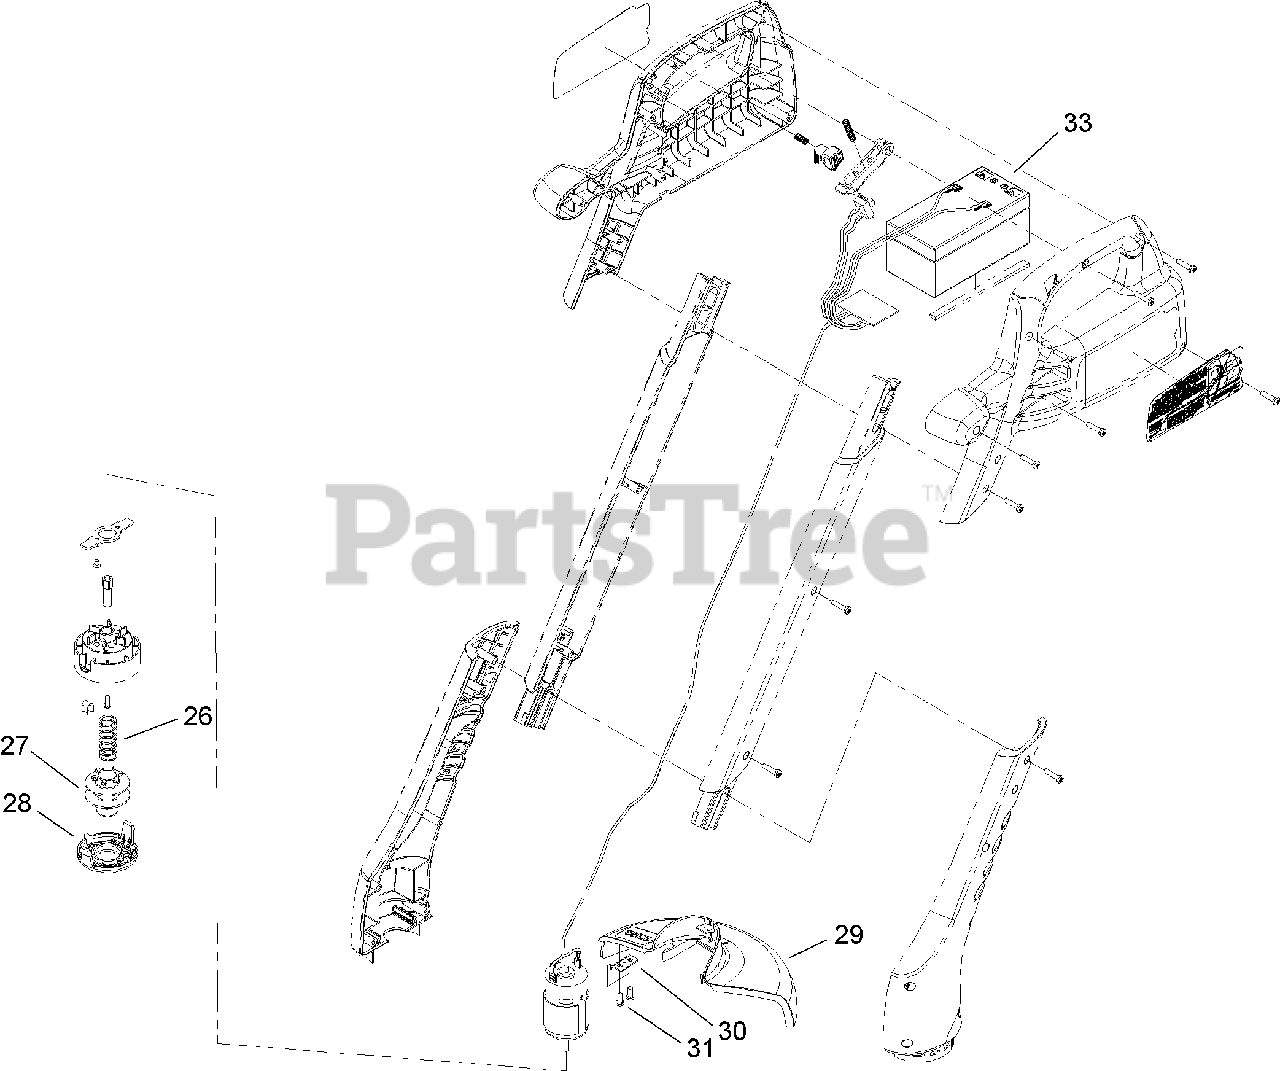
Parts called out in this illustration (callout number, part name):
26	SPRING-COMPRESSION
27	SPOOL ASM
28	CAP-SPOOL, 7 INCH
29	SHIELD-8 INCH TRIMMER
30	BLADE-CUTOFF
31	SCREW-PLASTIC THREAD FORM
33	BATTERY ASM
